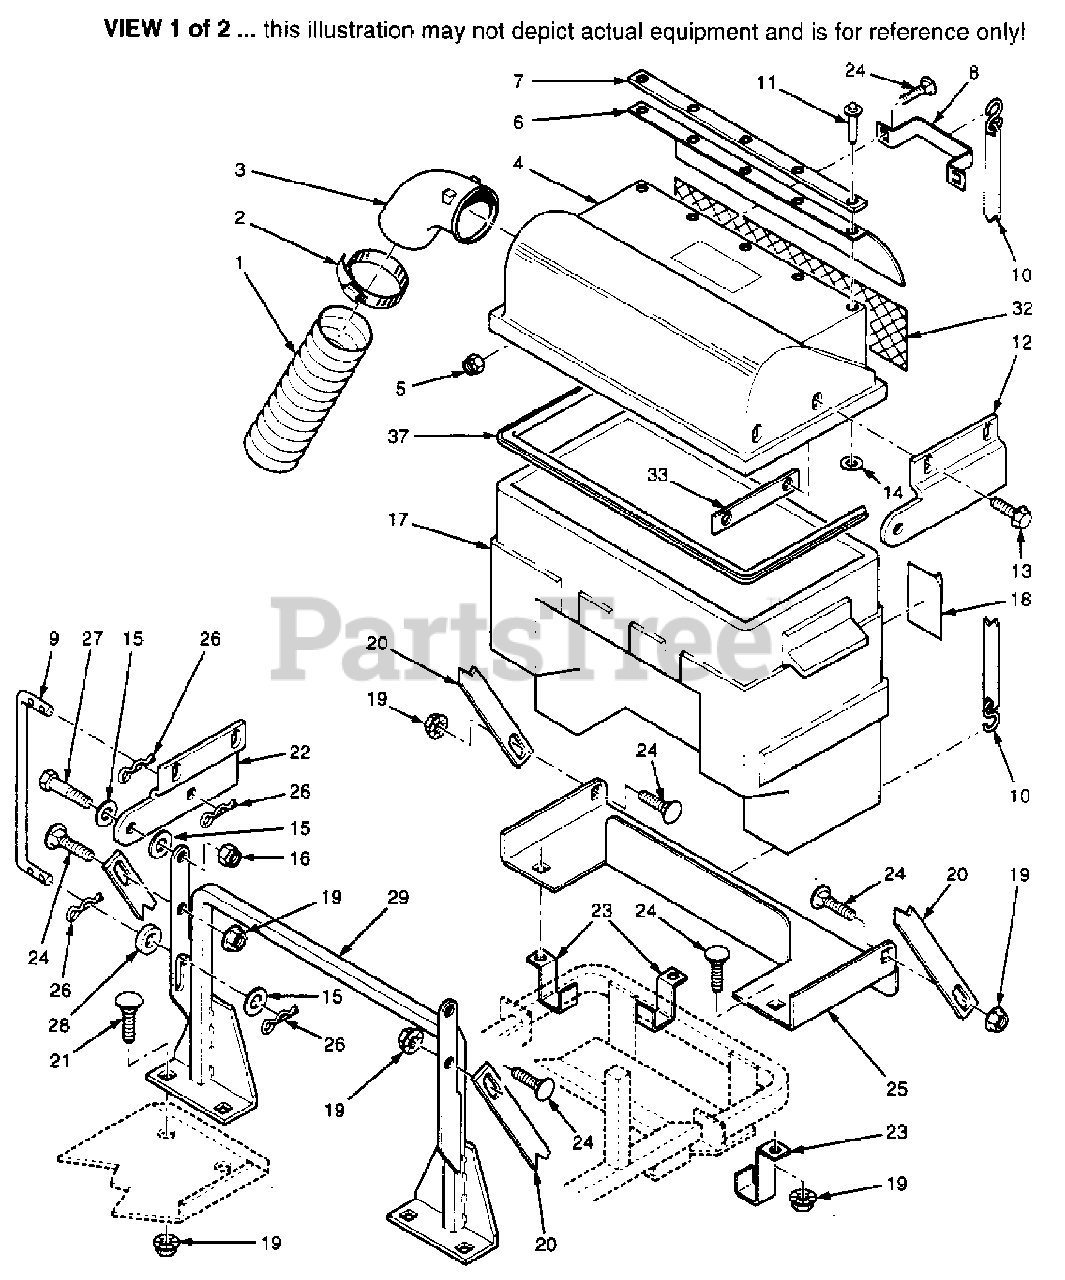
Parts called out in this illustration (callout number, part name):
1	HOSE, 6" X 48"
2	CLAMP, HOSE
3	ELBOW, GRASS CATCHER(INCL. ITEMS 6, 7, 11
4	COVER ASSEMBLY, GRASS CATCHER
5	NUT, ELASTIC STOP 5/16-18
6	DEFLECTOR, GRASS CATCHER
7	BACKING PLATE, DEFLECTOR
8	HANDLE
9	ROD, COVER SUPPORT
10	STRAP, RUBBER
12	HINGE, LH
13	CAPSCREW, SERR. FLANGE 5/16-18 X .75
14	WASHER, POP RIVET
15	FLAT WASHER, 3/8(.391 X .938 X .105)
16	NUT, ELASTIC STOP 3/8-16
17	HOPPER, GRASS CATCHER W/DECAL
18	DECAL, HOPPER
19	NUT, SERR. FLANGE 5/16-18
20	BRACE
21	CARRIAGE BOLT, 5/16-18 X 1.00
22	HINGE, RH
23	CLAMP, TRAY
24	CARRIAGE BOLT, 5/16-18 X .75
26	HAIR PIN, .080 DIA X 1.19
27	BOLT, HEX HEAD 3/8-16 X 1.50
28	FLAT WASHER, 3/8(.375 X 2.00 X .60)
29	SUPPORT FRAME WELDMENT
32	SCREEN
33	PLATE, HINGE BACKING
37	SEAL, RUBBER
